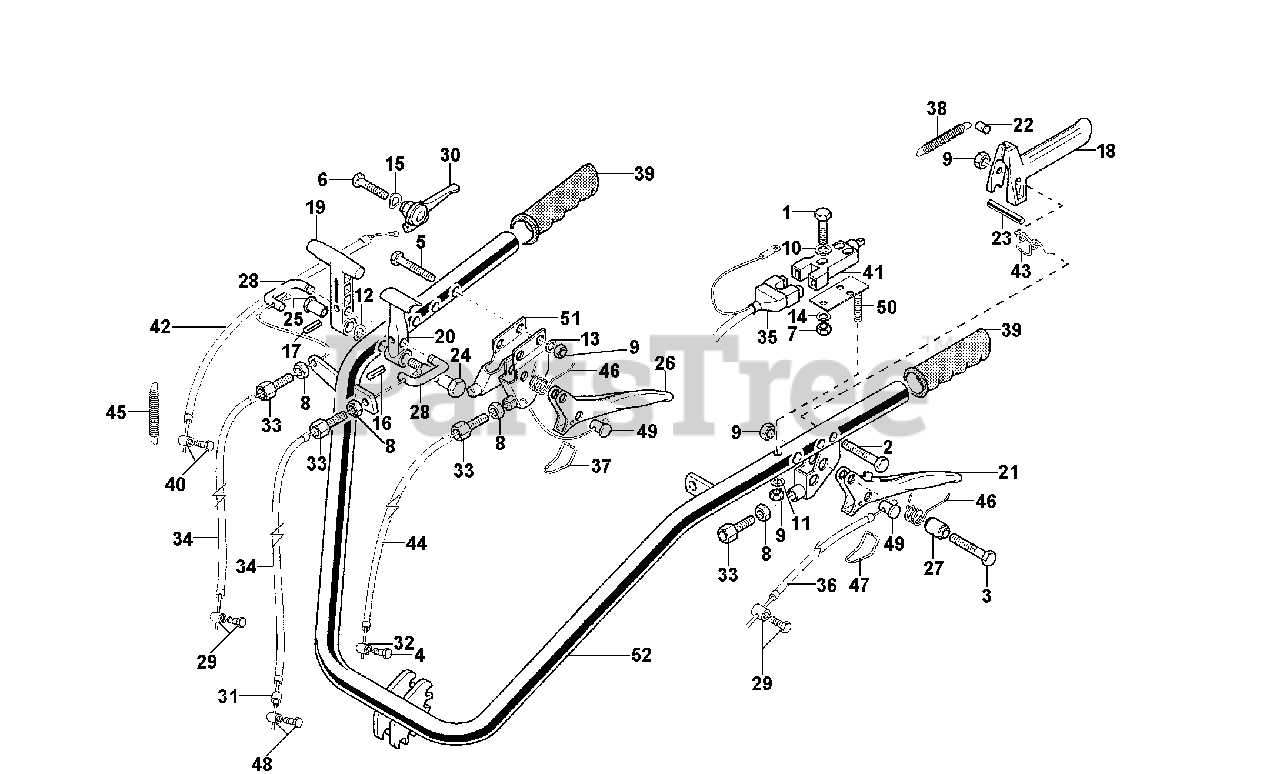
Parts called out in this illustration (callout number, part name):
1	SCREW, M4X25
2	SCREW, M6X45
3	SCREW, M6X25
4	SCREW, M6X16
5	SCREW, M6X35
6	SCREW, M8X35
9	NUT, SELF LOCKING, M6
10	FLAT WASHER, M4.3
11	WASHER, FLAT 6.4
13	WASHER, LOCK, M6.4
14	LOCK WASHER, M4.3
15	WASHER, LOCK, M8.4
16	PIN, LOCKING M4X20
17	PIN, LOCKING, M4X20
18	MOTOR STOP LEVER
19	REVERSER LEVER
20	LEVER DIFFERENTIAL LOCKING
21	CLUTCH LEVER
23	LEVER STOP FOR MOTOR STOP
25	DRILLED PIN
27	LEVER SPACER
29	CLAMP, CABLE
30	LEVER, ACCELERATOR
32	PIN, CABLE CLAMP
33	SCREW, ADJUSTING M8
34	CABLE, REVERSE
35	SWITCH WIRING HARNESS
36	CLUTCH CABLE
40	CLAMP, CABLE, VANGARD
41	STOP SWITCH
42	THROTTLE CABLE, VANGARD
43	MOTOR STOP LEVER SPRING
44	CABLE, BRAKE
45	SPRING, KOHLER
46	LEVER SPRING
48	CABLE CLAMP
50	SWITCH PLATE
51	COUPLING FOR DOUBLE LEVER
